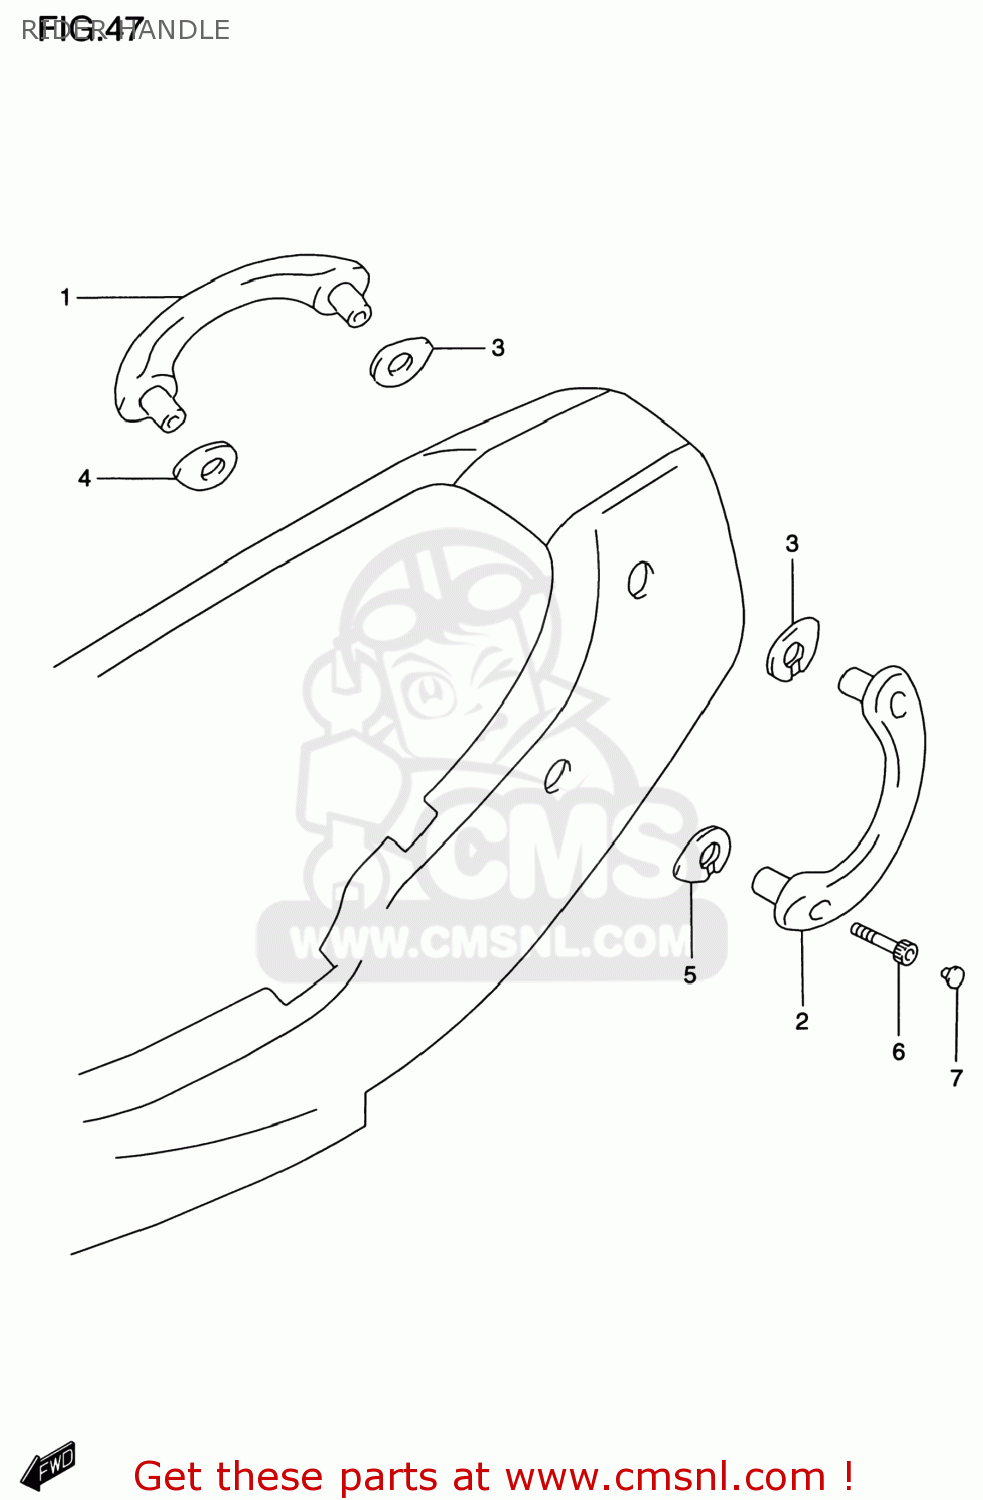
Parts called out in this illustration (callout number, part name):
1	HANDLE,PILLION RIDER,R
2	HANDLE,PILLION RIDER,L
3	CUSHION,PILLION HANDLE UPR
4	CUSHION,PILLION HANDLE LWR,R
5	CUSHION,PILLION HANDLE LWR,L
6	BOLT
7	CAP(OD:14.5)
